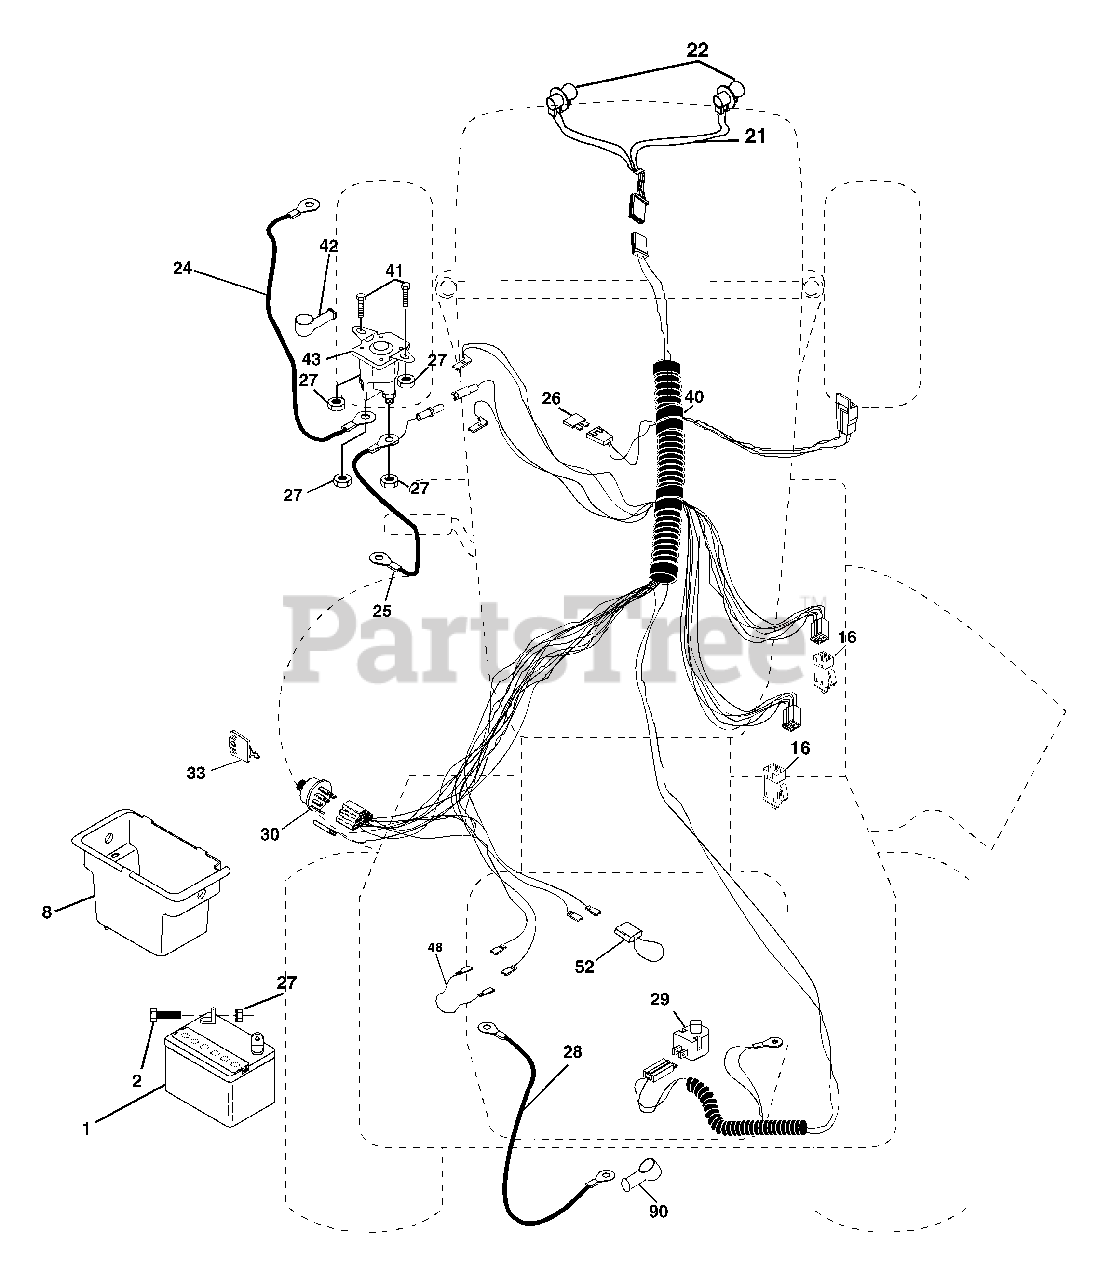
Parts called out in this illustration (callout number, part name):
1	Battery 12 Volt 28 Amp
2	Bolt Hex Hd 1/4-20unc X 3/4
8	Box Battery
16	Switch Interlock Push -In
21	Harness Asm Light W/4152J
22	Bulb Light #1156
24	Cable Battery 6 Ga 16" red
25	Cable Battery 6 Ga Red 44" W/16W
26	Fuse 20 AMP
27	Nut Keps Hex 1/4-20 unc
28	Cable Ground 6 Ga 12" black
29	Switch Plunger Nc Gray
30	Switch Ign
33	Key Ign
40	Harness Ign
41	Bolt Blk Fin Hex 1/4-20 X 1/2
42	Cover Terminal Red
43	Solenoid
48	Adapter Ammeter
52	Protection Wire Loop
90	Cover Terminal
